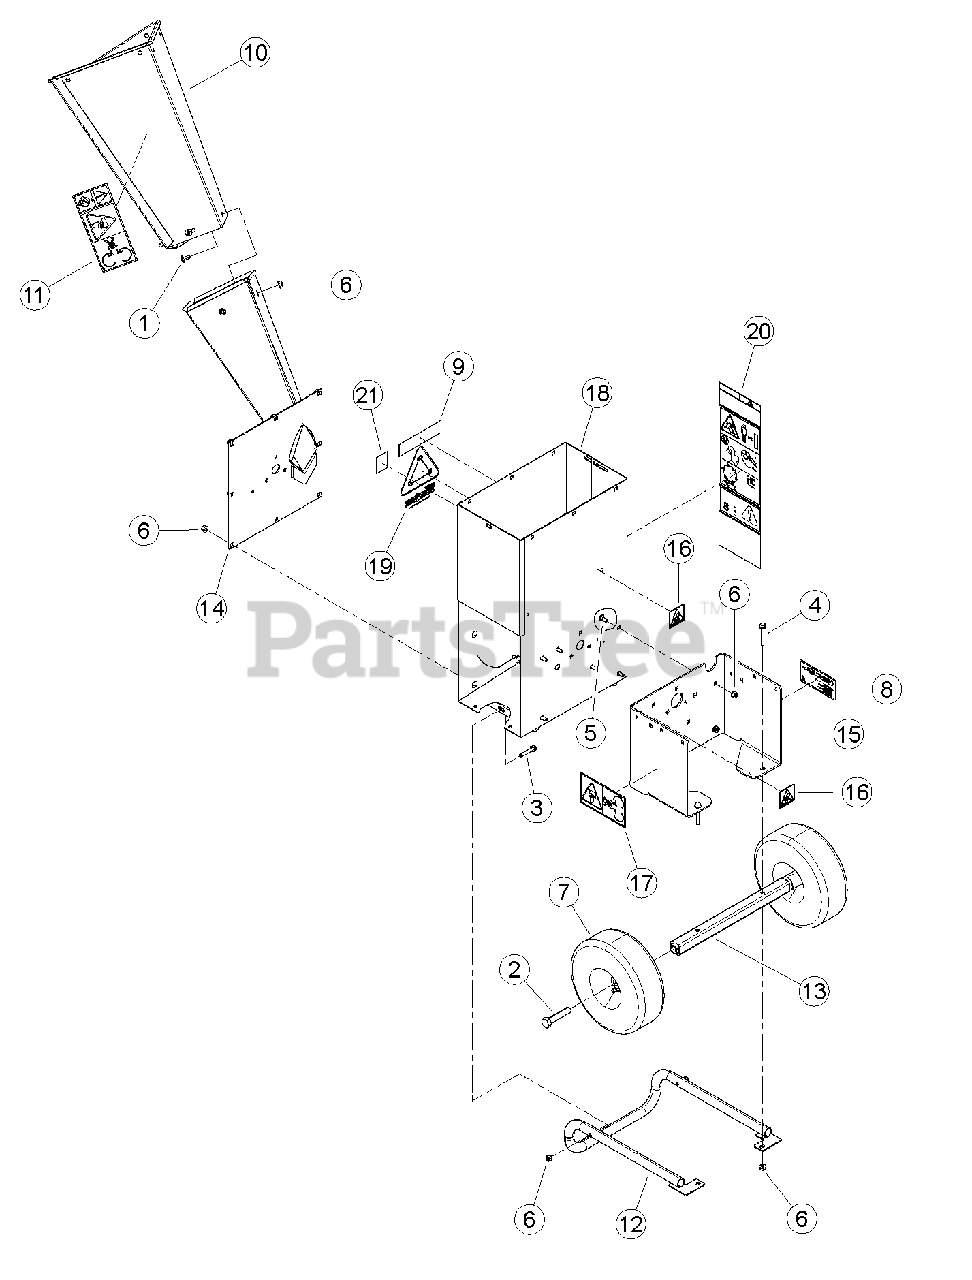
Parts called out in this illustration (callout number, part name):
1	BOLT, 5/16-18 X 3/4 CRG GR5 SN
2	BOLT, 5/8 X 3 HEX GR5 ZP
3	BOLT, 5/16 X 1-3/4 FLANGE NC
4	BOLT, 5/16 X 2-1/4 FLANGE NC
5	BOLT, 5/16 X 3/4 CRG GR5 NC ZP
6	NUT, 5/16-18 NYLOCK-FLANGE
7	ASSEMBLY, WHEEL 410/350-4
8	DECAL, SC3420XE CE INFO AND NOISE
9	DECAL, MODEL SC3420
10	ASSEMBLY, 3" CHIPPER CHUTE EXTENSION
11	DECAL, 3" CHIPPER CHUTE
12	WELDMENT, SUPPORT LEG LONG
13	WELDMENT, AXLE 3 IN CHIPPER
14	WELDMENT, CHIPPER CHUTE
15	ASSEMBLY, BASE 3 IN CHIPPER SERVICE PART
16	DECAL, SHIELD DANGER ISO
17	DECAL, BLADE DANGER ISO
18	ASSEMBLY, 3" C/S WIDE BODY SERVICE PART
19	DECAL, SHRED IT
20	DECAL, 3" CHIPPER BODY SIDE
21	DECAL, ECHO BEARCAT QR CODE
